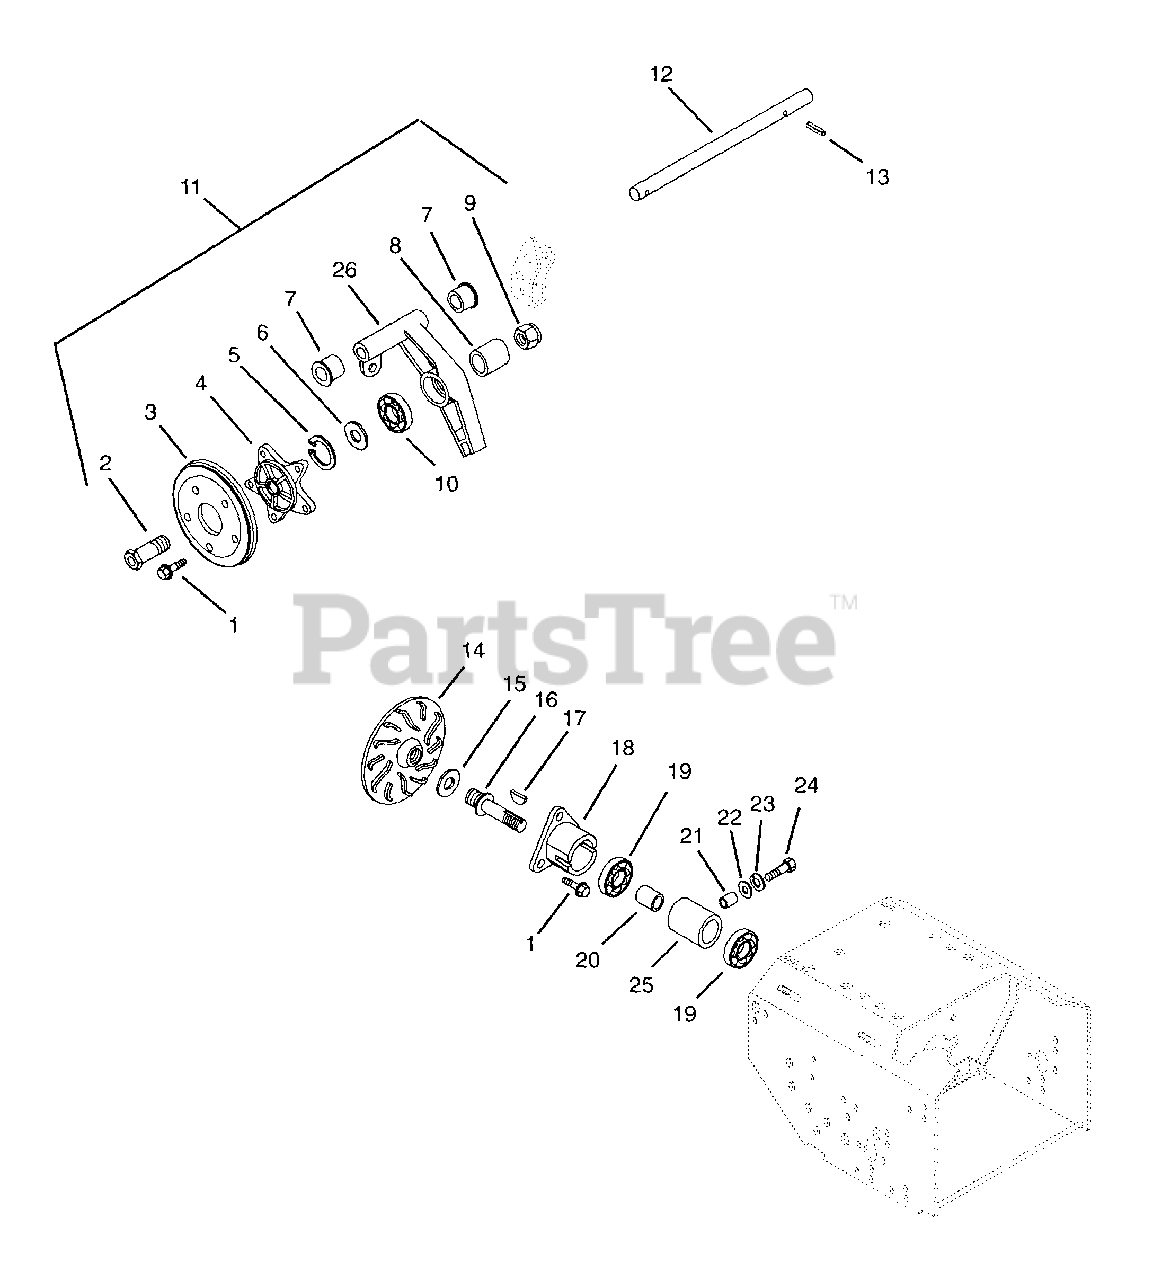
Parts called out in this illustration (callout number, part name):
1	@SCR-TAP .31-18X.50 HWH TR YWZ
2	SPINDLE HUB
3	FRICTION DISC
4	DISC HUB
5	RG-RTNG-INT 1.750X.062
6	WSHR-FL-STL .880X1.250X.062YWZ
7	BSHG-FLG .625X.750X.500X.875BR
8	BSHG-SLV .882X1.250X.531
9	NUT-LK-NYL .875-14 YWZC
10	BRG-BALL .876 X 1.750 X .50
11	FRICTION WHEEL ASSEMBLY
12	SHAFT, CARRIER
13	PIN-ROLL .156X1.00
14	DRIVE PLATE
15	DRIVE DISC SPACER 1.3X.76X.19
16	SPINDLE
17	KEY-WDRF .125X.500X.203 SAE 3
18	HOUSING MOUNT
19	BRG-BALL .625X1.375X.43
20	BEARING SPACER
22	@WSHR-FL-STL.344X.688X.065YWZC
23	@WSHR-LK .31X.078 REG YWZC
24	@BLT-HEX .31-18X1.00 GR5 YWZC
25	SPINDLE HOUSING
26	CARRIER
